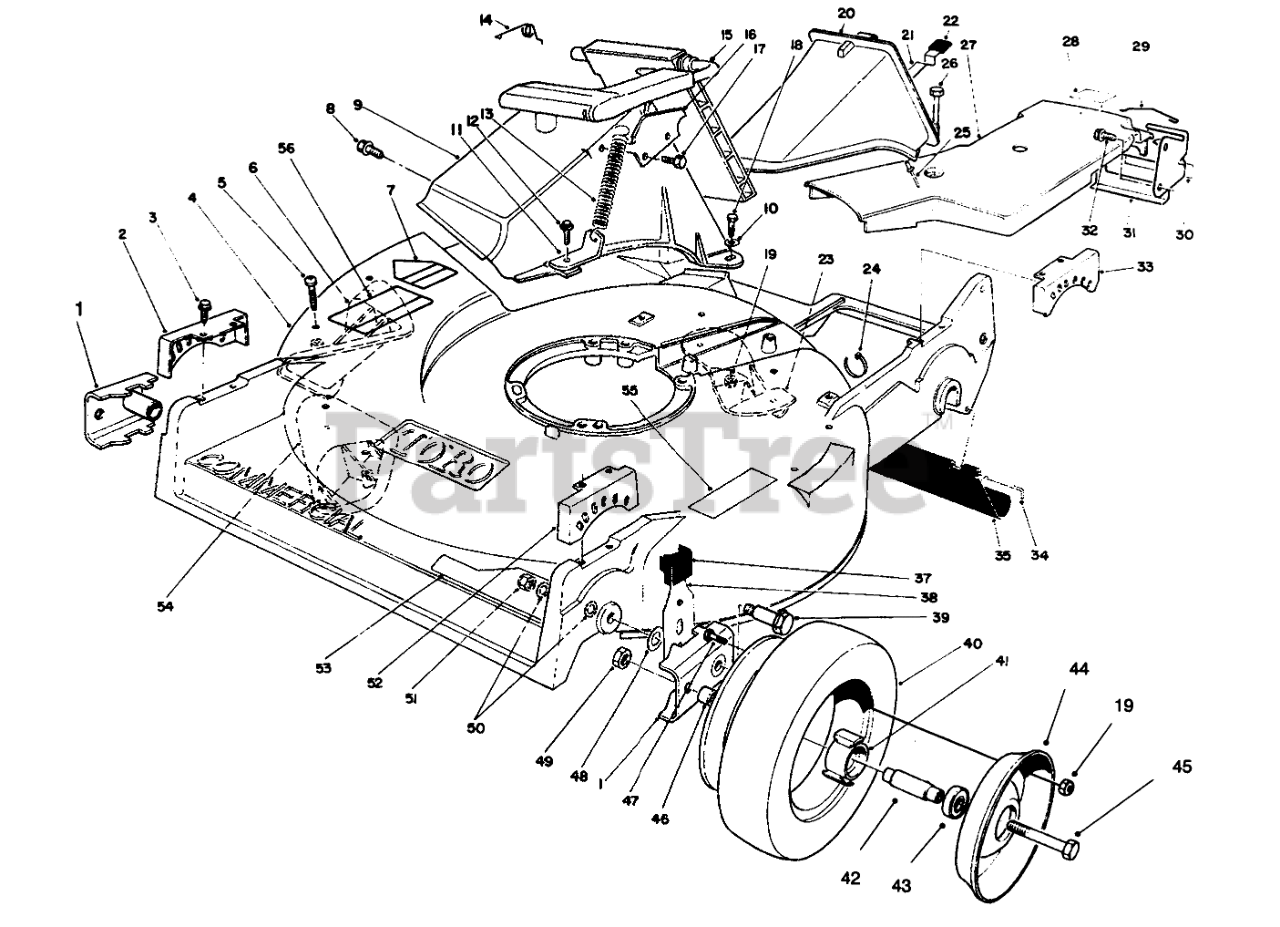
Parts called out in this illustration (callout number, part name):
1	ARM-PIVOT, FRONT
2	QUADRANT-FRONT, RH
3	SCREW-HWHTF
4	Housing-Commercial (Incl. Ref. #5-7, 23, &54-56)
5	SCREW-PPH
6	KICKER-RH
7	DECAL-DANGER
8	SCREW AND WASHER ASM
9	DISCHARGE TUNNEL
10	WASHER-FLAT
11	BRACKET-SPRING
12	SCREW-HWH
13	SPRING-DOOR
14	RETAINER-DOOR
15	DOOR ASSEMBLY
16	DOOR LATCH PLATE
17	SCREW-PLASTITE
18	SCREW-HH
19	NUT-LOCK, NI
20	Plug-Discharge (Incl. Ref. #21, 22, & 25)
21	LATCH-PLUG, DISCHARGE
22	GRIP-LATCH
23	KICKER-REAR
24	TIE-CABLE
25	RIVET-HEAD, FLAT
26	SCREW-HHFTF
27	COVER-BELT
28	LABEL-GREASE
29	RETAINER-CABLE
30	DECAL-POSITION, GEAR
31	BRACKET-ADJUSTMENT, TRACTION
32	SCREW-HWHTF
33	QUADRANT-REAR, LH
34	ROD-SHIELD
35	SHIELD-TRAILING
37	KNOB-ARM
38	FRONT SPRING ARM ASM
39	BOLT-WHEEL
41	HUB-BEARING
42	SPACER-BEARING
43	BEARING-WHEEL
44	Wheel-Half
45	SCREW-HH
46	SPACER-WHEEL
47	SCREW-HH
48	WASHER-THRUST
49	NUT-LOCK, CONE
50	WASHER
51	NUT-LOCK
52	QUADRANT-FRONT, LH
53	DECAL - RECYCLER
54	KICKER-FRONT
55	DECAL-INSTRUCTION, SAFETY
56	DECAL - DANGER, COVERS
